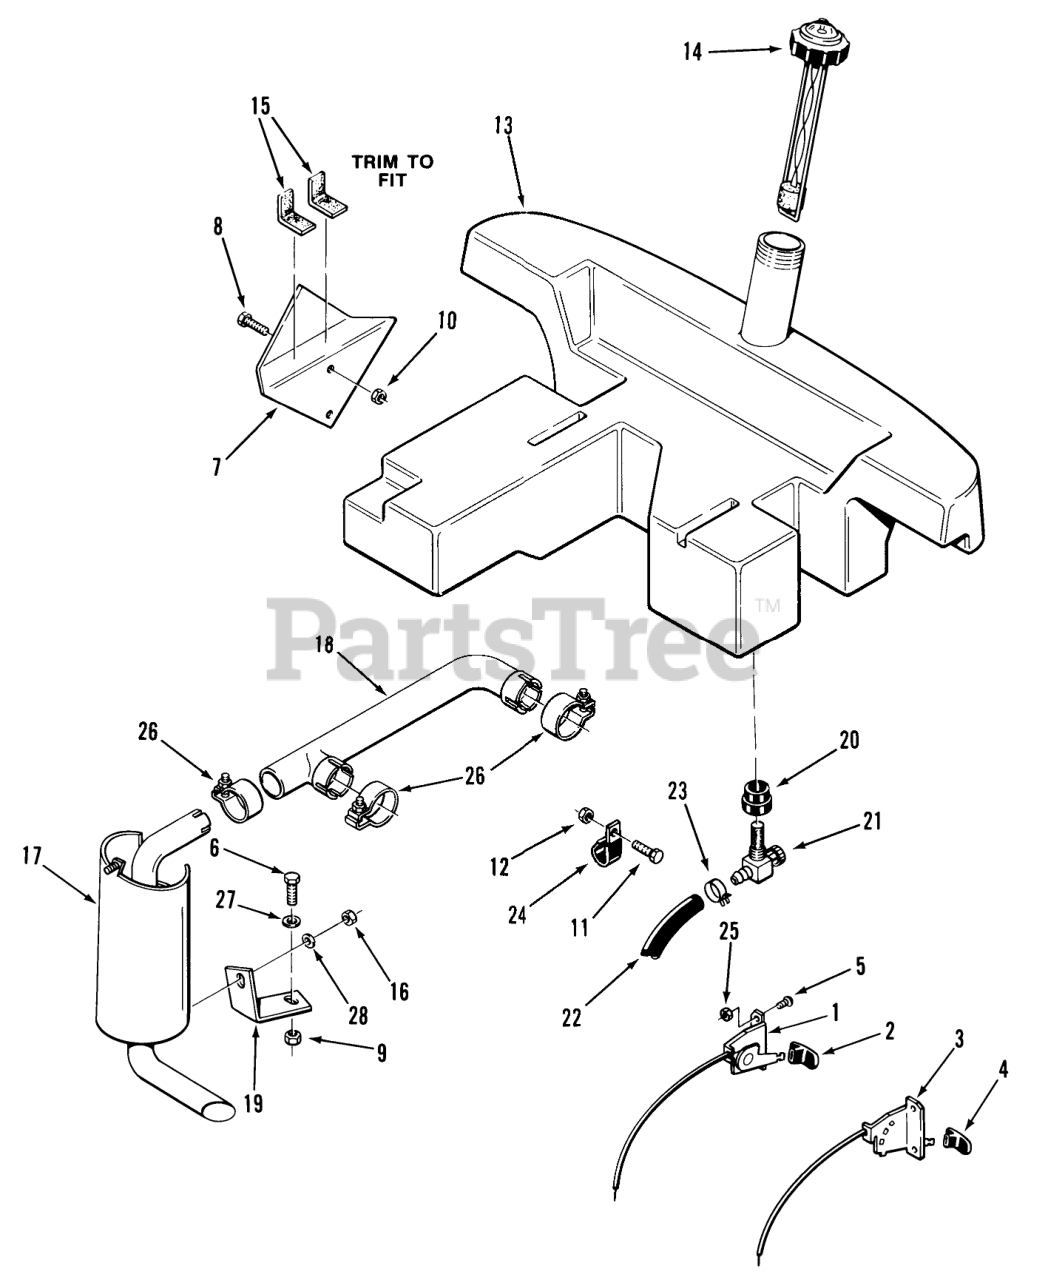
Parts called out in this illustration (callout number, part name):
1	CONTROL-THROTTLE
2	KNOB-THROTTLE
3	CONTROL-CHOKE
4	KNOB-CHOKE
5	RIVET-4
5	Screw
6	BOLT
7	Support Bracket
8	BOLT
9	Nut
10	Nut
11	Bolt
12	Nut
13	Fuel Tank
14	ASSY GAGE CAP
15	TRIM-CONSOLE
16	Nut
17	Muffler
18	MANIFOLD-EXHAUST
19	Muffler Mounting Bracket
20	BUSHING
21	VALVE-FUEL
22	Fuel Line-69 in. Long
23	Clamp
24	CLIP
24	CLAMP
25	Nut
26	CLAMP-MUFFLER
27	Washer
